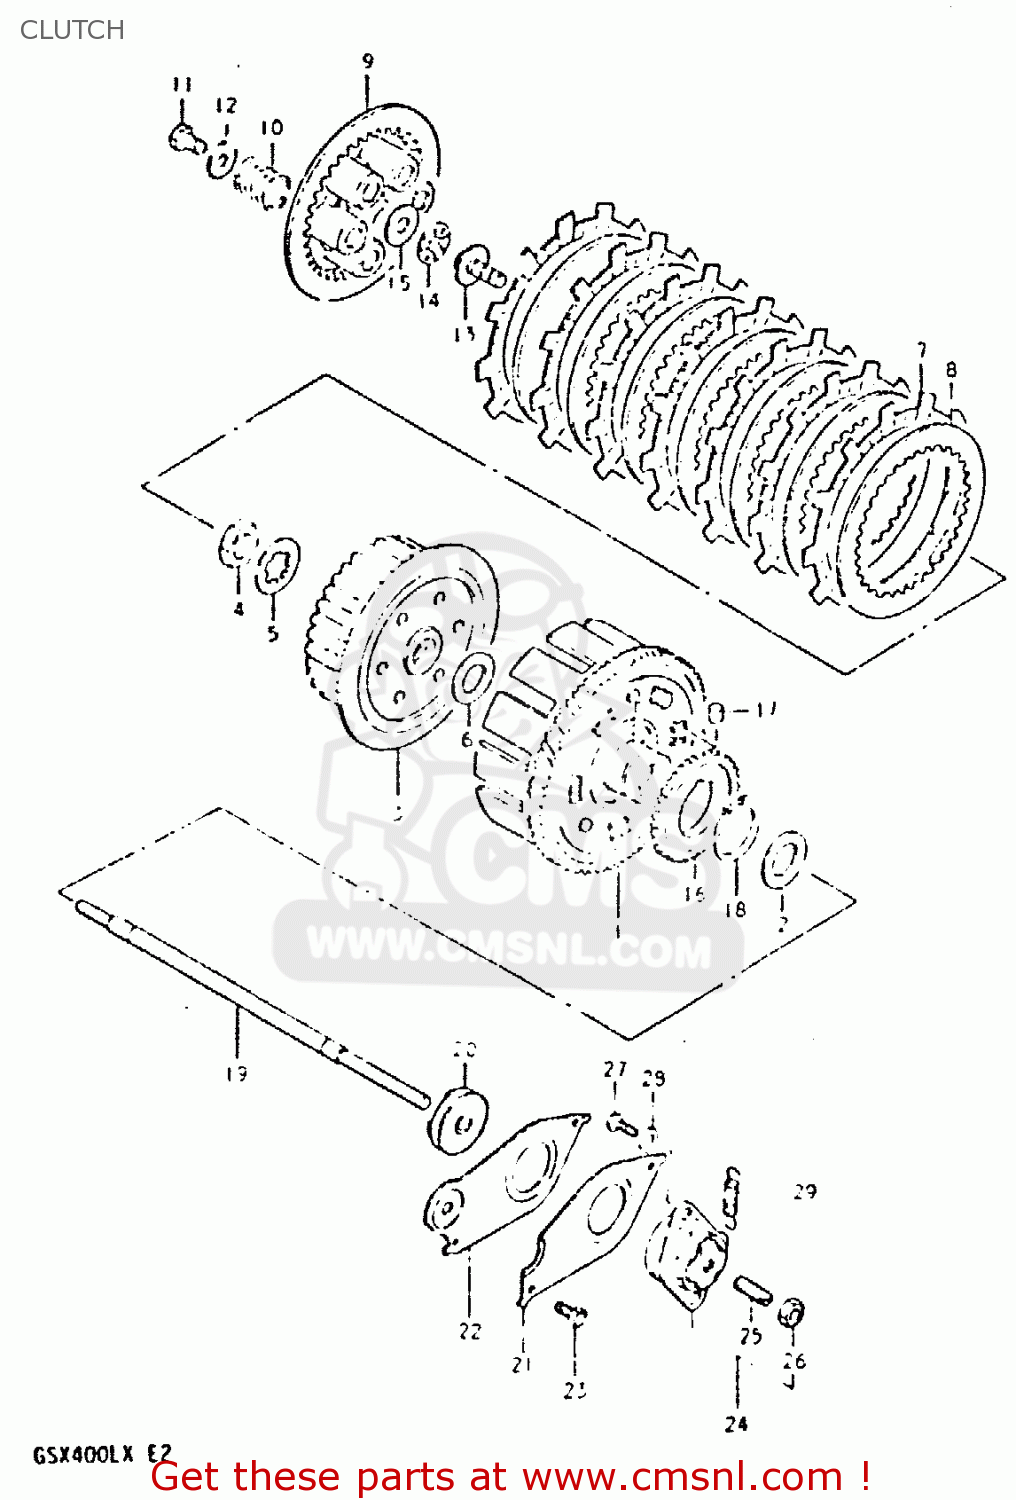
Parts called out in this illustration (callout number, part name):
1	GEAR ASSEMBLY,PRIMARY DRIVE
2	WASHER
3	HUB,CLUTCH SLEEVE
4	NUT (20MM)
5	WASHER,LOCK
6	WASHER(20X44X3)
7	PLATE,CLUTCH DRIVE (MCA)
8	PLATE,CLUTCH DRIVEN (NAS)
9	DISC,CLUTCH PRESSURE
10	SPRING
11	BOLT, UPPER
12	WASHER
13	PIECE,CLUTCH PUSH
14	BEARING(15X28X2)
15	WASHER
16	GEAR,OIL PUMP DRIVE
17	PIN(6X6)
18	CIRCLIP
19	ROD,CLUTCH PUSH
20	SEAL,OIL(6X18X7)
21	PLATE,CLUTCH PUSH ROD
22	PLATE,CLUTCH PUSH ROD
23	BOLT
24	SCREW ASSEMBLY,CLUTCH RELEASE
25	SCREW
26	NUT 6MM
27	SCREW
28	WASHER
29	SPRING
